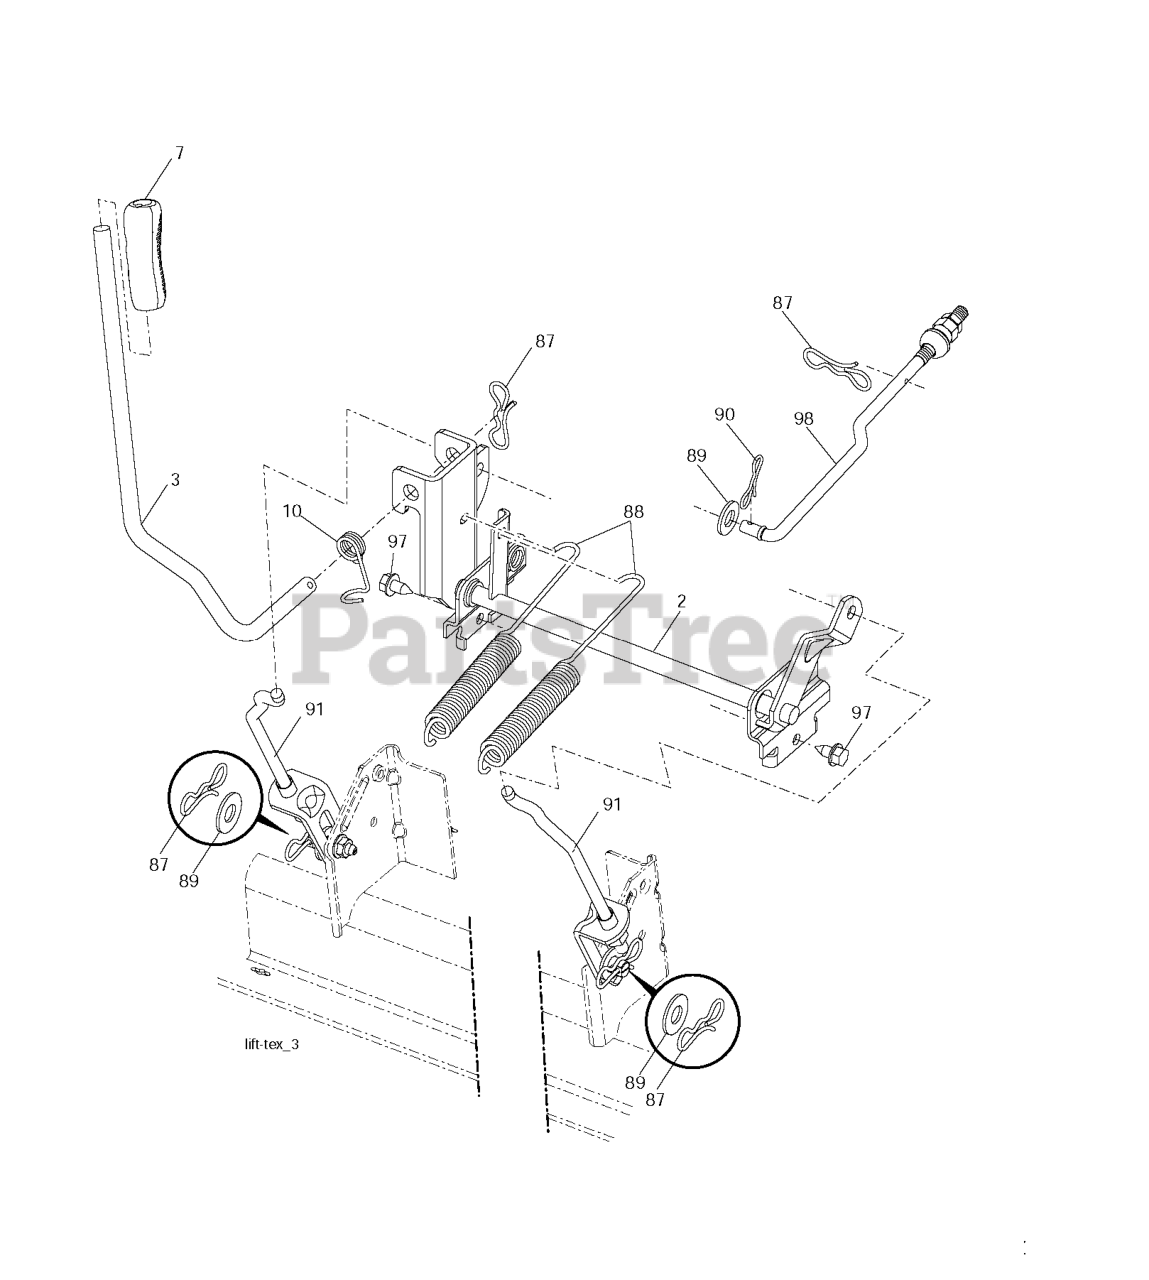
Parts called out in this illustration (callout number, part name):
2	SHAFT.ASM.LIFT.CROSS.H
3	LEVER.LIFT.HANDLE.GT
7	GRIP.HANDLE.LIFT.PVC.BLACK
10	SPRING.TORSION.LIFT.HANDLE
87	PIN.COTTER.7/16.BOW TI.
88	SPRING.LIFT.ASSIST.GT2
89	WASHER.CLEAR.ZINC
90	PIN.COTTER.5/16.BOW TI
91	LINK.ASM.LIFT.54"TG
97	SCREW 3/8-16X3/4
98	LINK.ASM.SUSP.FRONT.MWR.10.5
